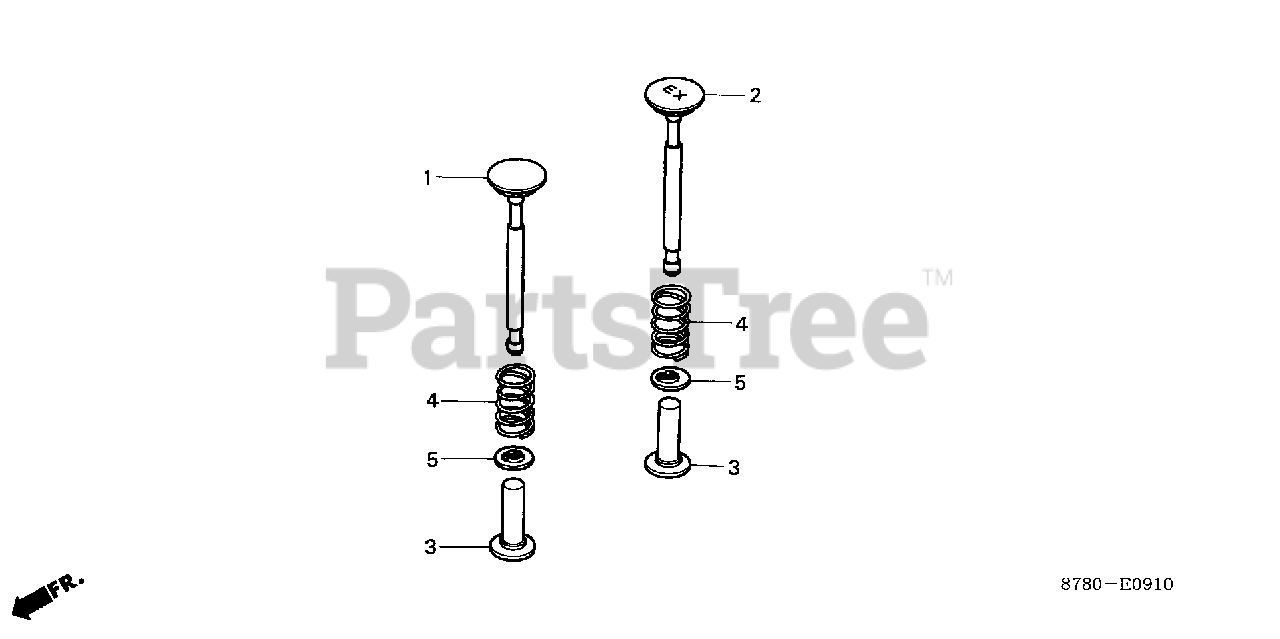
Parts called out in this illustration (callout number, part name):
1	VALVE, IN.
2	VALVE, EX.
3	LIFTER, VALVE
4	SPRING, VALVE (NOT AVAILABLE)
5	RETAINER, VALVE SPRING
